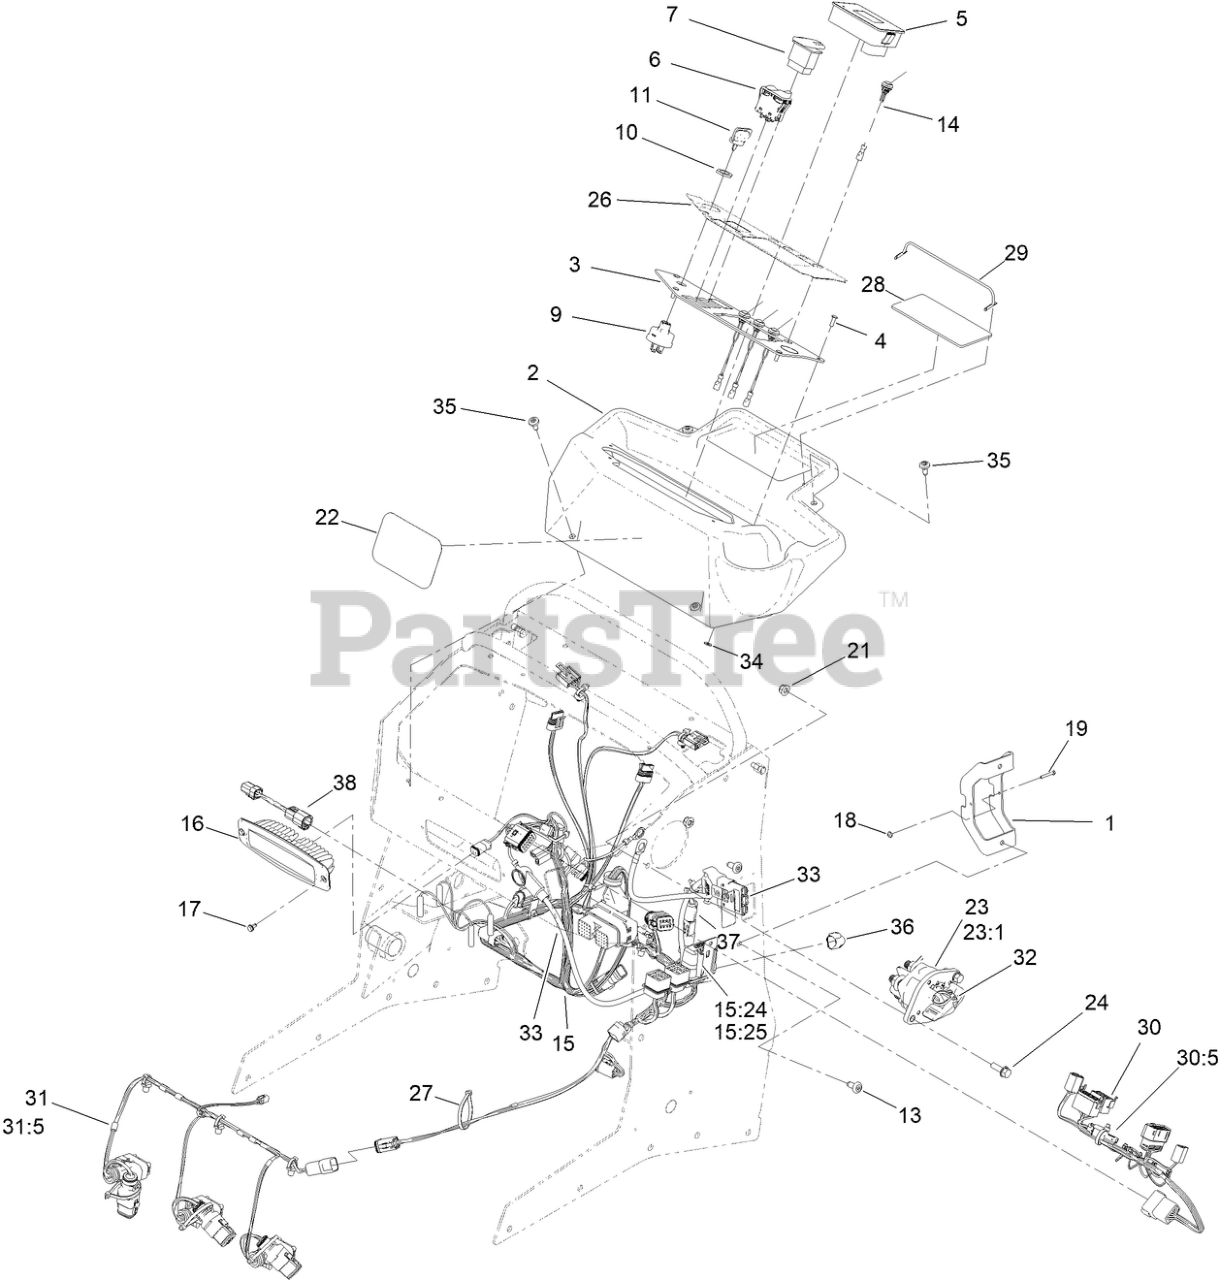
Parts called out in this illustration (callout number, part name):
1	BRACKET-CHARGER, DUAL
2	DASH-CONTROL PANEL
3	PLATE-CONTROL PANEL
4	RIVET-POP
5	TDM 2002
6	SWITCH-ROCKER, (ON)-ON-OFF
7	SWITCH
9	SWITCH-KEY, SPST
11	KEY-IGNITION
14	SWITCH-PUSHBUTTON
15	HARNESS-WIRE, MAIN
15:24	FUSE-MINI BLADE, 2 AMP
16	MOUNT-FLUSH, LIGHT
17	SCREW-HWH
18	NUT-HEX
19	SCREW
21	NUT-HF, NI
22	DECAL
23	SWITCH-DISCONNECT
23:1	NUT-HF
24	SCREW-HHF
26	DECAL-PANEL, CONTROL
27	TIE-CABLE
28	PAD-RUBBER, W/ADHESIVE
29	STRAP-ELASTIC
30	HARNESS-WIRE, CONTROL PANEL
30:5	RESISTOR-120 OHM
31	HARNESS-WIRE, DECK
31:5	RESISTOR-120 OHM
32	TIE-CABLE
33	HARNESS-WIRE, CHARGER PORT
34	WASHER-PLAIN
35	SCREW-SHOULDER
36	CAP-PLUG, 3 WAY
37	FERRITE-SNAP ON
38	HARNESS-WIRE, JUMPER
